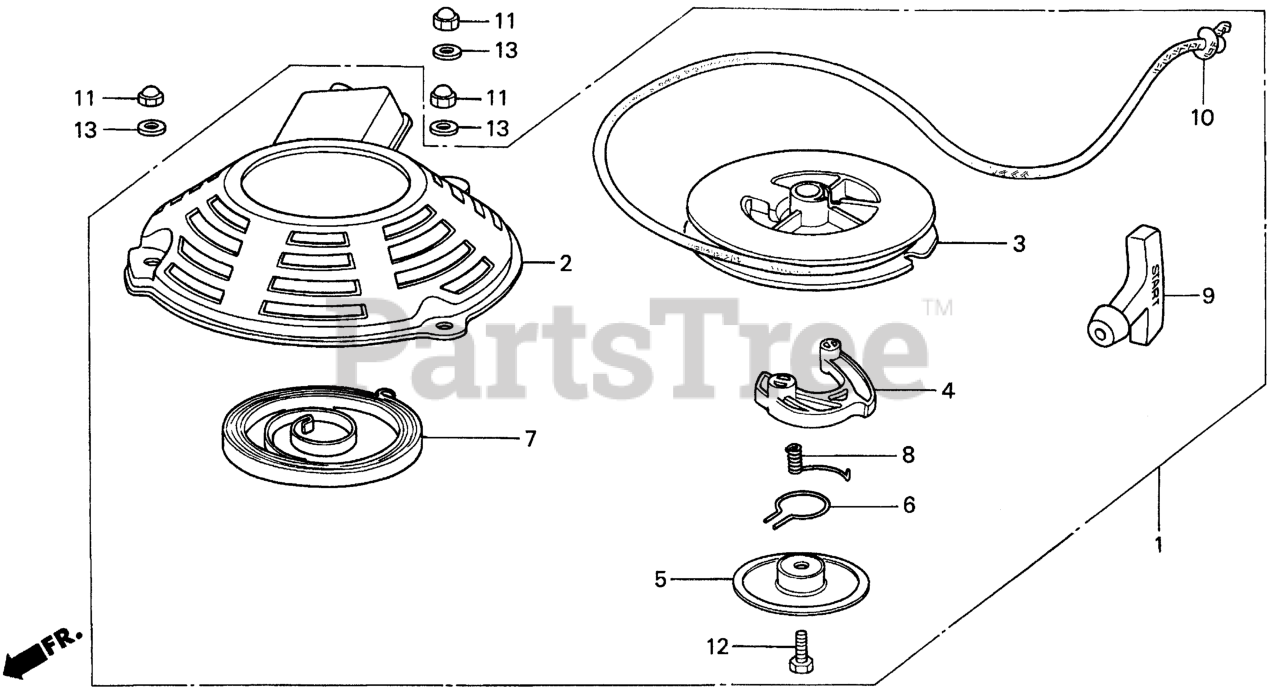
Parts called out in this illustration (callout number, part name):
1	STARTER ASSY., RECOIL *G144* (GARDEN GREEN)
1	STARTER ASSY., RECOIL *R8* (BRIGHT RED)
2	CASE, RECOIL STARTER *G144* (GARDEN GREEN)
2	CASE, RECOIL STARTER *R8* (BRIGHT RED)
3	REEL, RECOIL STARTER
4	RATCHET, STARTER
5	PLATE, FRICTION
6	SPRING, FRICTION
7	SPRING, RECOIL STARTER
8	SPRING, RETURN
9	KNOB, STARTER
10	ROPE, RECOIL STARTER (#4X91")
11	NUT, FLANGE CAP (5MM)
12	BOLT, HEX. (6X20)
13	WASHER, PLAIN (5MM)
